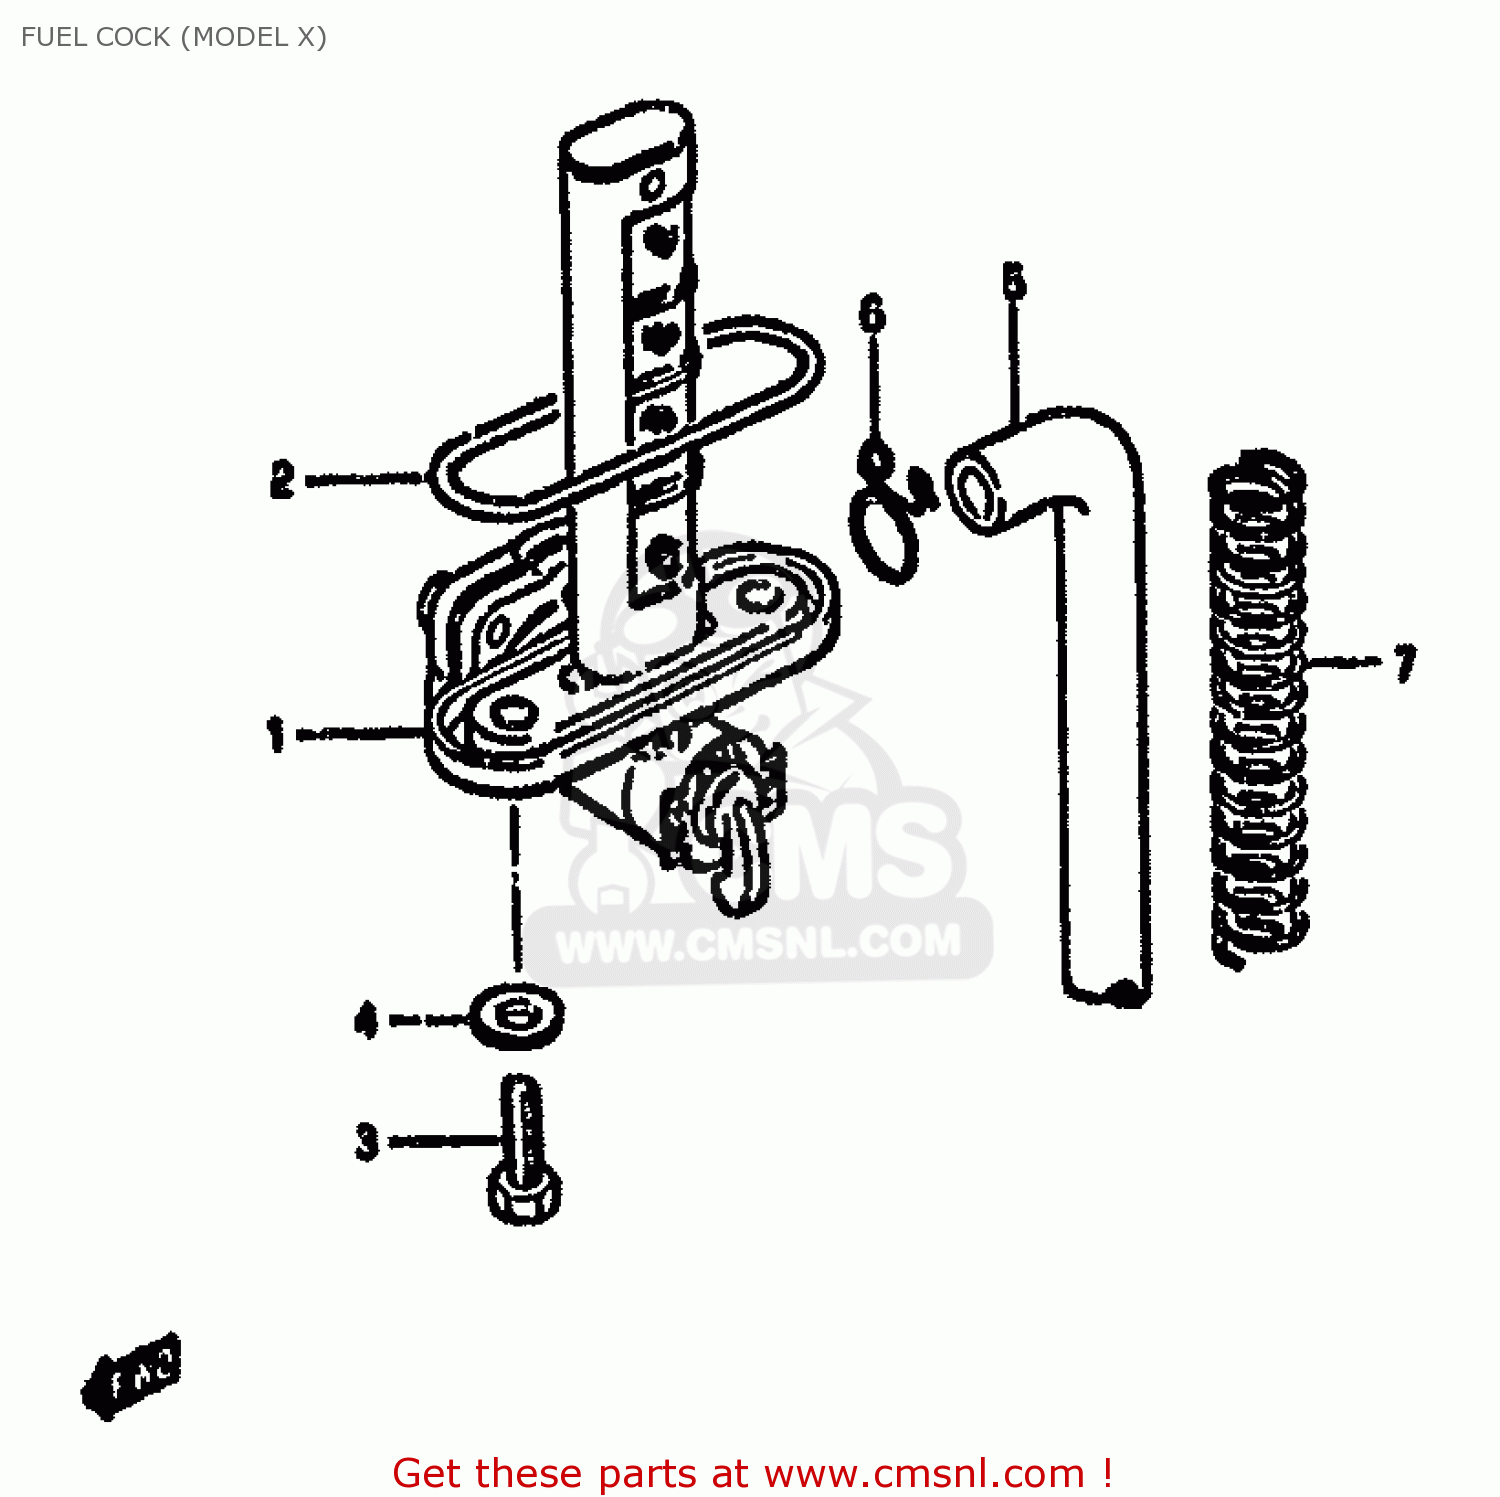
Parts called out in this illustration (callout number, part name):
1	COCK ASSEMBLY,FUEL
2	O RING
3	BOLT(6X20)
4	GASKET
5	HOSE
6	CLIP
7	SPRING
